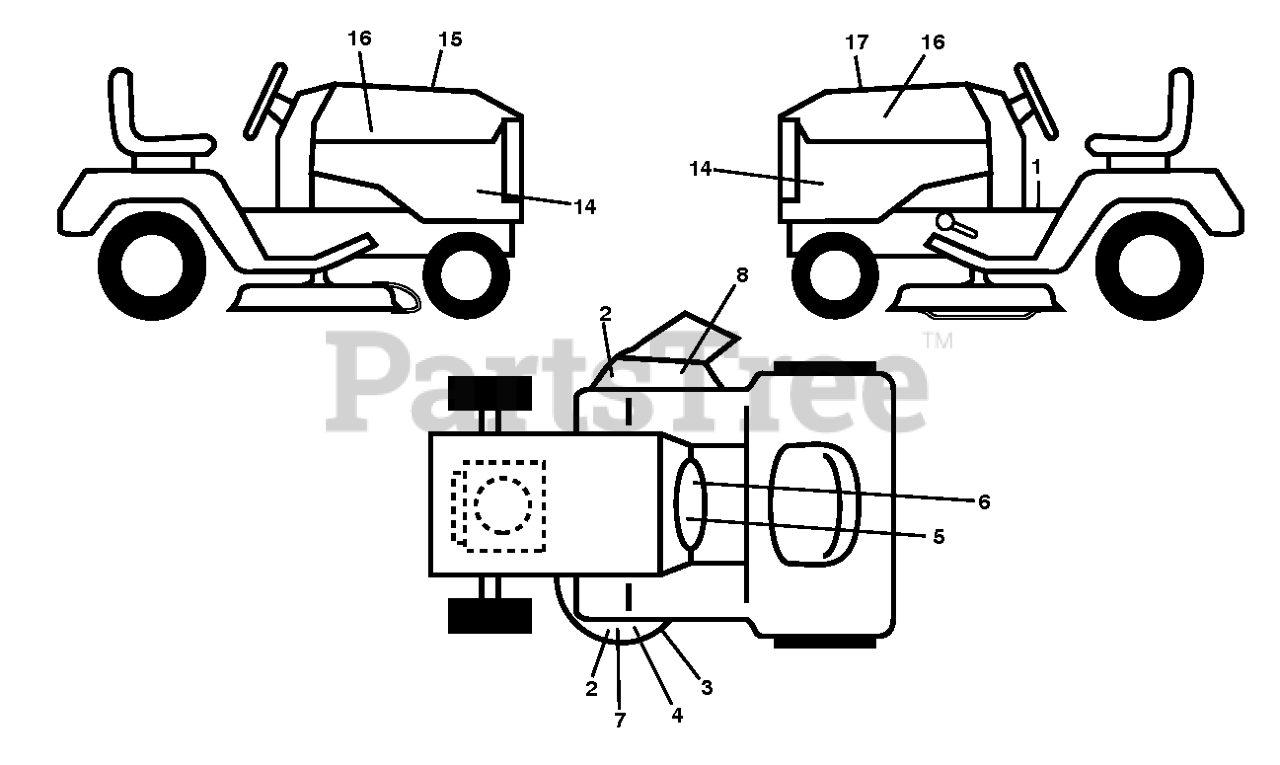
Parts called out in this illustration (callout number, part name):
1	DECAL.FENDER.WARNING.ENGLISH
2	DECAL.DECK.CLEARCUT.NOSTEP
3	DECAL BELT ROUTING DECAL DECAL
4	DECAL DECK DECAL DECAL.DECK.WA
5	DECAL CARB DECAL EMISS.CA.HUSQ
6	DECALS.WARN.CA.SPKARREST/PROP
7	DECAL.54DECK.CLEARCUT.VER2.18
8	DECAL.TRACT/ZTR.DECKWARN.HUSQ
14	DECAL TRACTOR SIDE PANEL DECAL
15	DECAL.WARNING.CUST.RESP.E85.
16	DECAL.BADGE.170MM.TEXTLOGO.
17	DECAL G730.54F.KAW FR730.TGB
